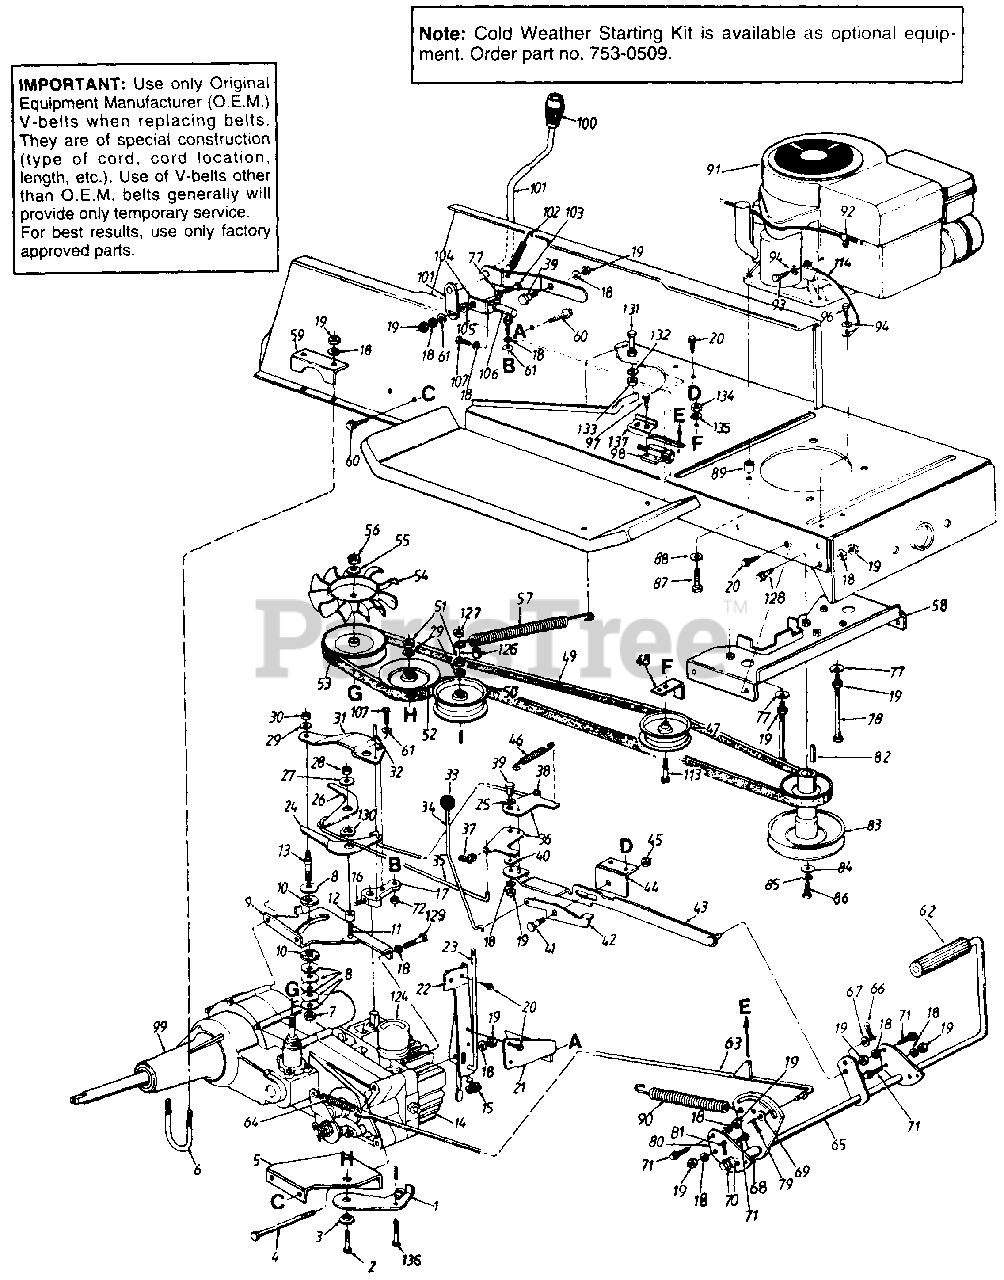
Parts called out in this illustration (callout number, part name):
1	Idler Bracket
2	Hex Bolt 3/8-16 x 2.0" Lg.
3	Shld. Spacer .625" I.D.
4	Hex Bolt 5/16-18 x 4.5" Lg. (Gr. 5)
5	Idler Plate
6	U-Bolt 5/16-18 x 1.75" Lg.
7	Hex L-Nut 3/8-24 Thd.
8	Bell-Wash. .40" I.D. x 1.13"
9	Mounting Bracket
10	Friction Washer
11	Rib Neck Bolt 5/16-24 x .84" Lg.
14	Hydrostatic Pump
15	Rubber Washer .33" I.D.
17	Pintle Shift Lever
18	L-Wash. 5/16" I.D.
19	Hex Nut 5/16-18 Thd.
20	Hex TT-Tap Scr. 1/4-20 x .5"
21	Reinforcement Plate
22	Transmission Torque Brkt.
23	Release Valve Rod
24	Reverse Arm
25	Spring Washer .625" I.D.
26	Forward Arm
27	Fl-Wash. .344" I.D. x 1.0"
28	Hex Cent. L-Nut 5/16-24 Thd.
29	L-Wash. 3/8" I.D.
30	Hex Nut 3/8-24 Thd.
31	Pintle Arm Ext. Plate
32	Roll Pin 1/4" Dia. x .75" Lg.
35	Connection Rod
36	Balancer Bracket
37	Rod End Clevis Clips - R.H.
38	Rod End Clevis Clips - L.H.
39	Shld. Bolt .437" Dia. x .268"
40	Fl-Wash. .344" I.D. x 1.12"
41	Shld. Bolt .437" Dia. x .35"
42	Lock-Up Bracket
43	Neutral Return Brkt. Ass'y.
45	Hex Cent. L-Nut 5/16-18 Thd.
46	Ext. Spring 2.5" Lg.
47	Idler Pulley 3.06" O.D.
51	Hex Nut 3/8-16 Thd.
52	Idler Pulley 4.0" O.D.
53	Transmission Pulley
55	Bell-Wash. .569" I.D. x 1.125"
56	Hex Jam Nut 9/16-18 Thd.
57	Extension Spring
58	Belt Guard Brkt. Ass'y.
59	Bracket
60	Hex Wash. Hd. B-Tap Scr. 5/16-18 x .5" Lg.
61	Flat Tooth Washer 5/16" I.D.
62	Foot Pad
63	Brake Rod Ass'y.
64	Ext. Spring 3.67" Lg.
65	Clutch Brake Pedal Ass'y.
66	Intern. Cotter Pin 5/16" Dia.
67	Fl-Wash. .385" I.D. x .62"
68	Spacer .63" I.D.
69	Fl-Wash. .385" I.D. x .62"
70	Fl-Wash. .635" I.D. x 1.0"
71	Hex Wash. TT-Tap Scr. 5/16-18 x 7/8" Lg.
72	Hex Nut 5/16-24 Thd.
77	Bell-Wash. .345" I.D. x .88"
78	Hex Bolt 5/16-18 x 4.0" Lg.
79	Cotter 3/32" Dia. x .75" Lg.
82	Sq.-Key 1/4" x 2.0"
83	Engine Pulley
84	Fl-Wash. 7/16" I.D. x 1.25"
85	L-Wash. 7/16" I.D. (H.D.)
86	Hex Bolt 7/16-20 x 1.5" Lg.
87	Hex TT-Tap Scr. 3/8-16 x 1.5"
88	Fl-Wash. .406" I.D. x 1.25"
89	Spacer .38" I.D. x 1.25" O.D.
90	Extension Spring 6.11" Lg.
91	Engine
93	Truss Mach. Scr. 5/16-18 x .75"
94	External L-Wash. 5/16" I.D.
96	Hex AB-Tap Scr. 5/16 x .75"
97	Truss B-Tap Scr. #10 x .5"
98	Safety Switch (Clutch)
101	Speed Selector Lever Ass'y.
102	Ext. Spring 2.75" Lg.
103	Hex Bolt 5/16-18 x 1.25" Lg.
104	Connection Brkt.
105	Shoulder Nut
106	Ball Joint 5/16-24 Thd.
107	Hex Bolt 5/16-24 x .75" Lg.
113	Hex Bolt 3/8-24 x 1.75" Lg.
114	Ground Wire 7.25" Lg.
124	Reservoir
126	Spacer .375" I.D. x .503"
127	Hex Jam Nut 3/8-16 Thd.
128	Hex TT-Tap Scr. 5/16-18 x .62"
129	Hex Bolt 5/16-18 x 4 3/4" Lg.
130	Spring Washer .625" I.D.
131	Hex Bolt 1/4-20 x 1.25" Lg.
132	L-Wash. 1/4" I.D.
133	Hex Nut 1/4-20 Thd.
134	Hex L-Nut 3/8-24 Thd.
135	Fl-Wash. .385" I.D. x .87"
136	Hex Bolt 3/8-16 x 2.5" Lg.
137	Switch Plate
